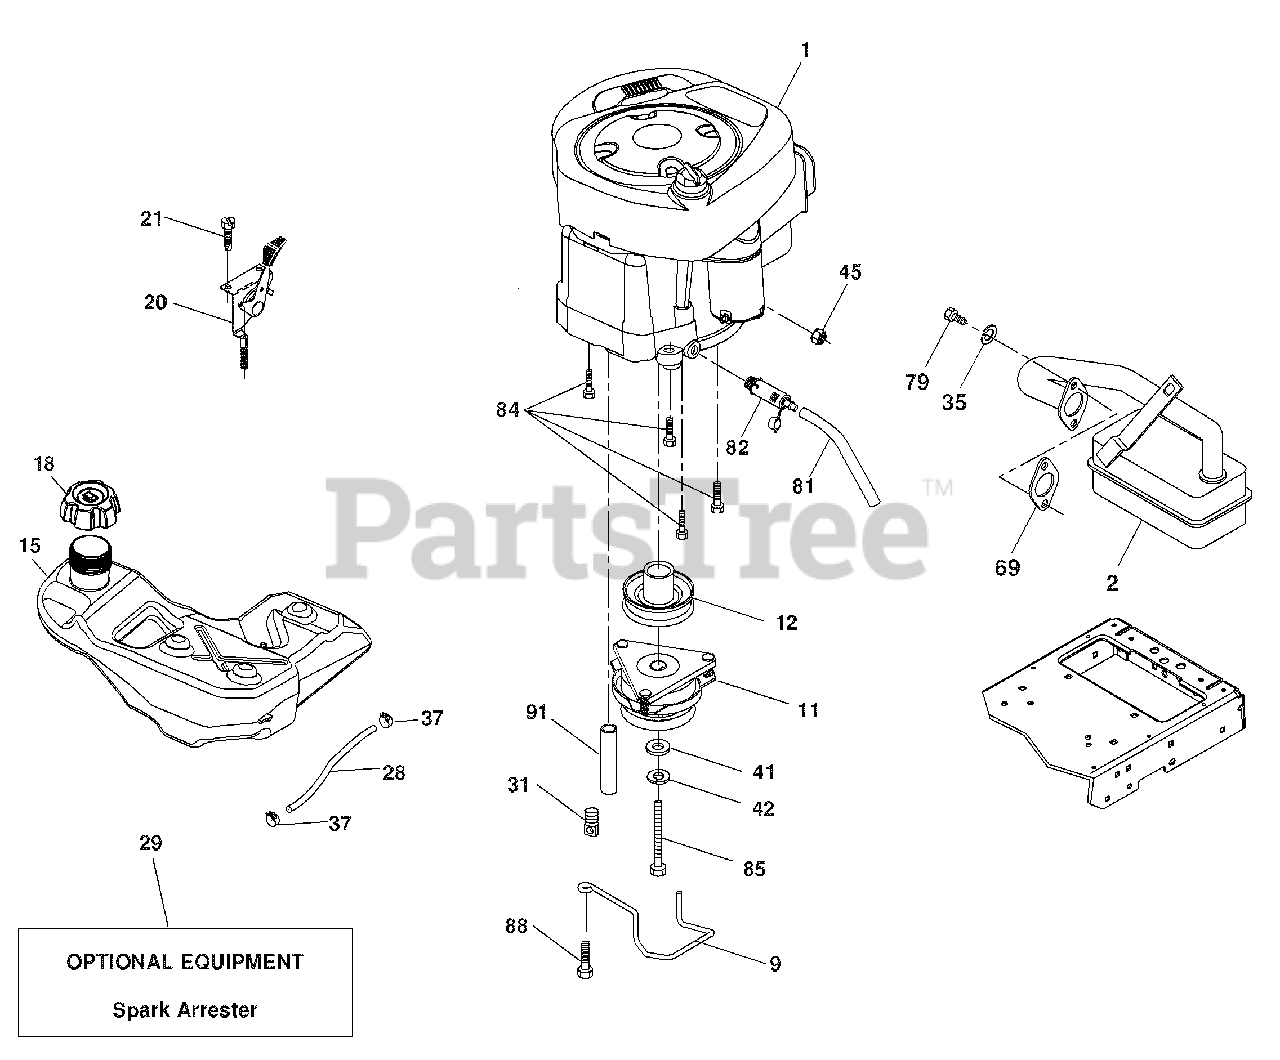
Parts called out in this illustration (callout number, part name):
9	Keeper Belt Engine
11	Clutch Ogura
12	Pulley Engine
15	Tank Fuel
18	Cap Asm
20	Control Throttle
28	Fuel Line
29	Spark Arrester Kit
31	Clip Push-In Hinged
34	Screw thd Cut 1/4-20 x 1/2
35	Washer Split
37	Clamp Hose
41	Washer 1-1/2 OD x 15/32 ID x .250
42	Washer Lock 7/16
45	Nut Keps Hex 1/4-20 unc
69	Gasket
79	Screw Socket Head 5/16-18 x .75
81	Tube Drain Oil Easy
82	Plug Drain Oil
84	Screw 3/8-16 x 1-1/4
85	Bolt Hex 7/16-20 x 4 x Gr. 5-1.5 Thr
88	Screw 3/8-16 x 1
